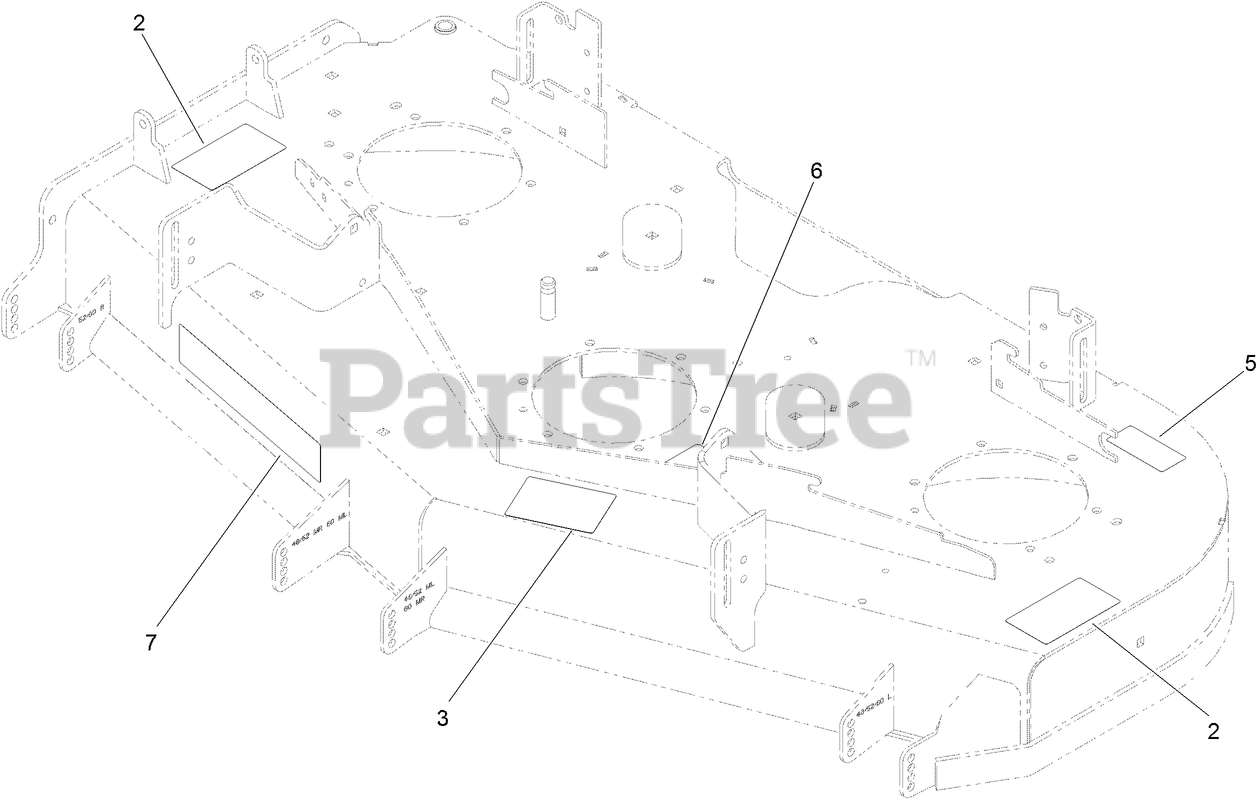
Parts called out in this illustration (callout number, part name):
2	DECAL-DANGER
3	DECAL-SCALP, ANTI
5	DECAL-BOLT TORQUE
6	DECAL-ROUTING, BELT
